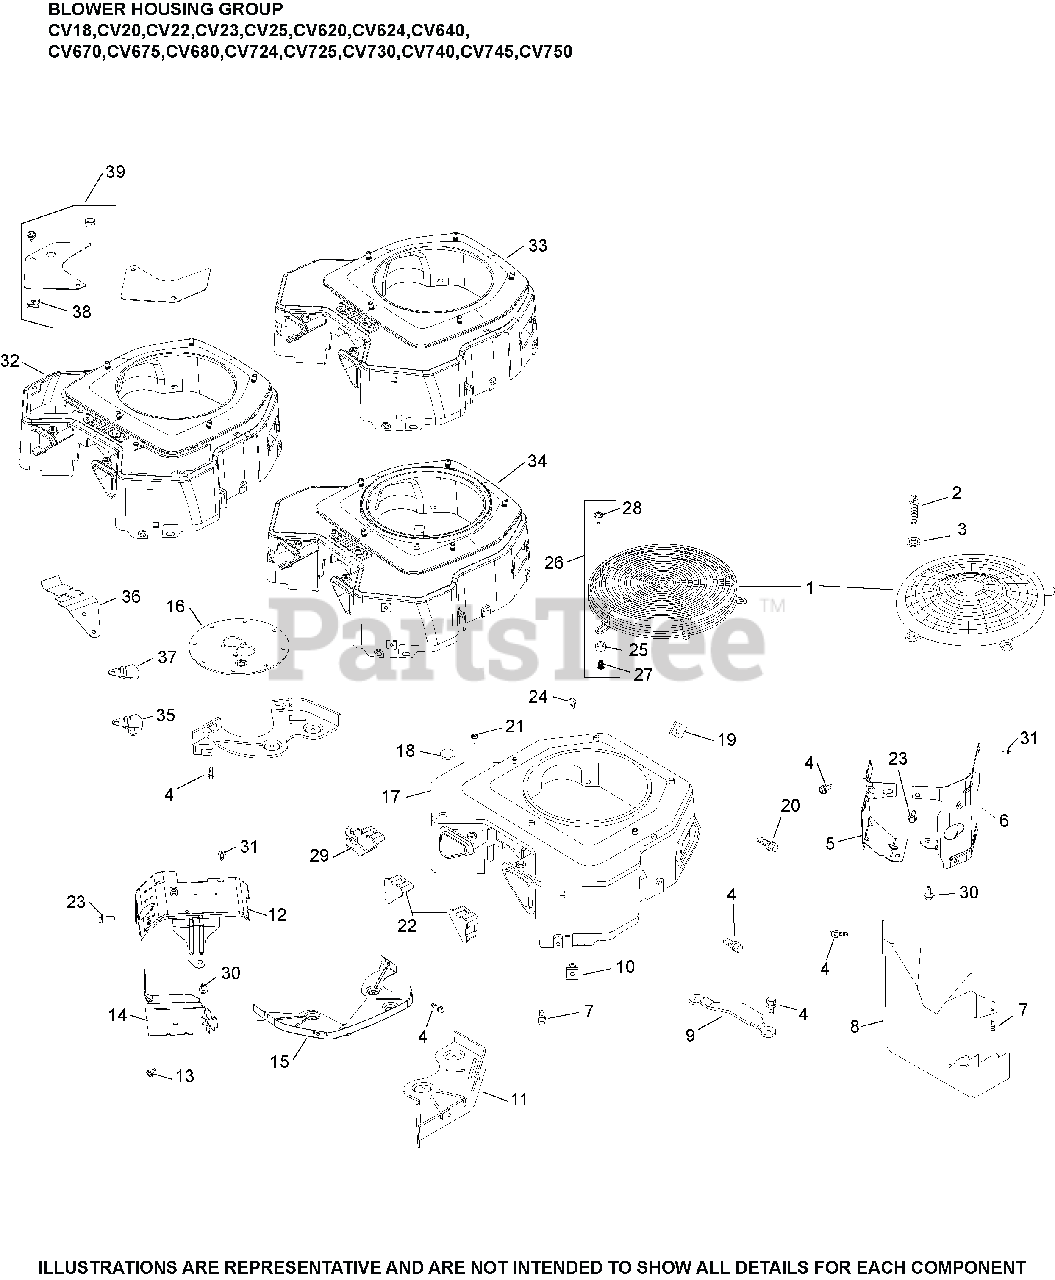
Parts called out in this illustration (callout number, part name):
5	BAFFLE, VALLEY #1 CYLINDER
6	KIT, CYL BAFFEL #2 SIDE
12	KIT, CYL BAFFEL #1 SIDE
14	BAFFLE, VALLEY #2 CYLINDER
15	KIT, BACKING PLATE
17	HOUSING, BLOWER
20	SCREW, THREAD FORMING
22	COVER, BLOWER HOUSING
23	SCREW, THREAD FORMING
24	SCREW, THREAD FORMING
27	INSERT, THREADED (M5)
28	SCREW, SEMS
30	SCREW, THREAD FORMING
31	SCREW, THREAD FORMING
38	CLIP, BAFFLE MOUNTING
39	KIT, ACCESS PANEL
